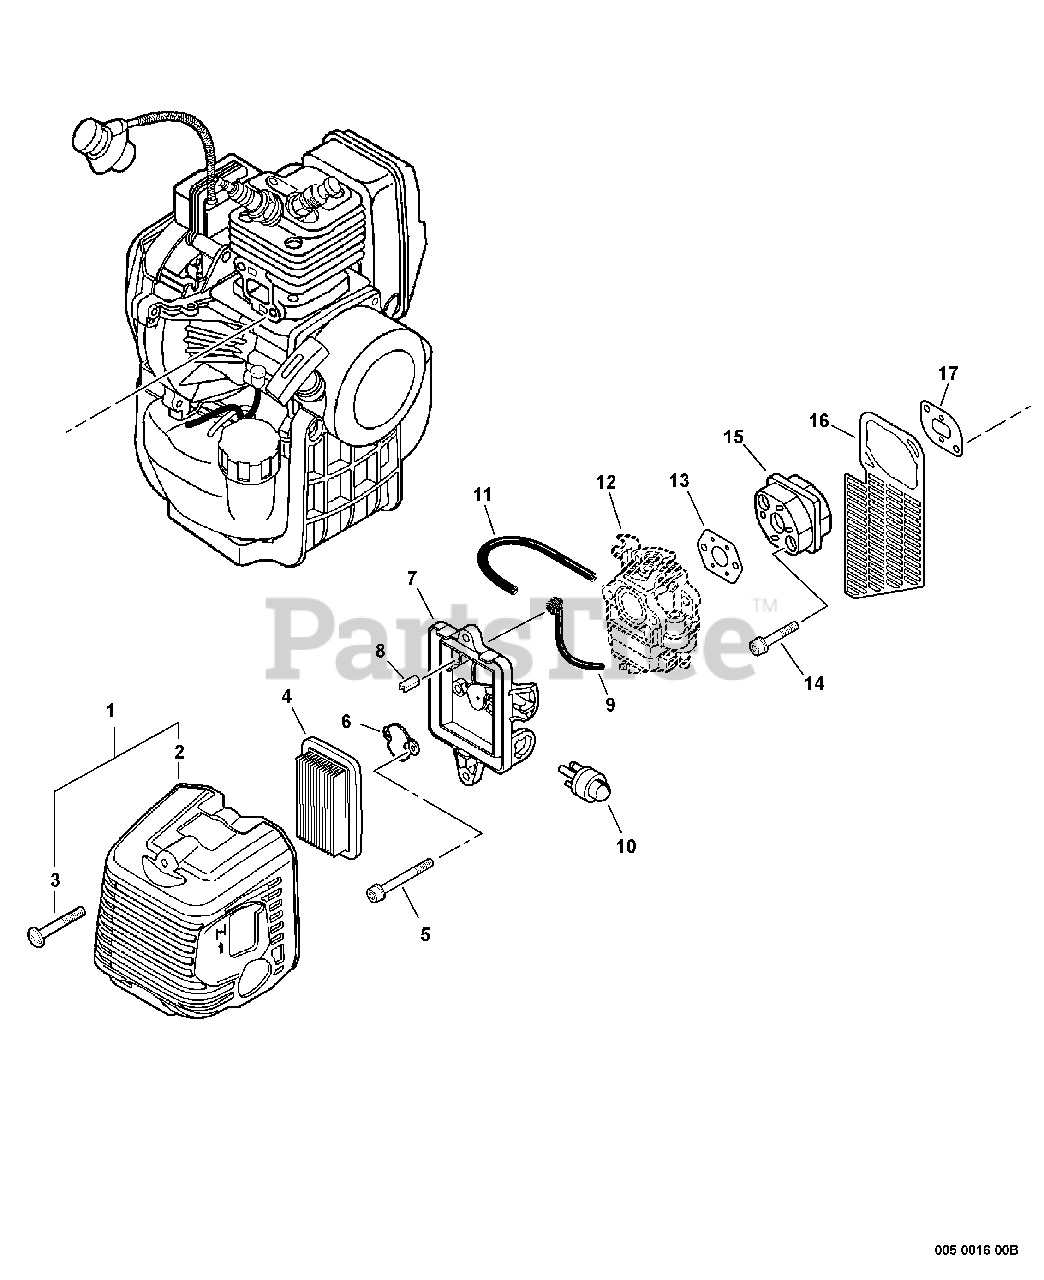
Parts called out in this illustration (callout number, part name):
1	AIR FILTER COVER ASSY
2	COVER, AIR FILTER
3	SCREW - 5X20
4	FILTER, AIR
5	SCREW - 5X55
6	PLATE, PREVENT
7	CASE, AIR FILTER
8	PIPE - INTAKE
9	PIPE - VENT
10	PUMP, PURGE
11	PIPE - 3X5X80 -- BLACK
12	CARBURETOR
13	GASKET, INTAKE
14	SCREW - 5X25
15	INSULATOR, INTAKE
16	GUARD, DEBRIS
17	GASKET, INTAKE
